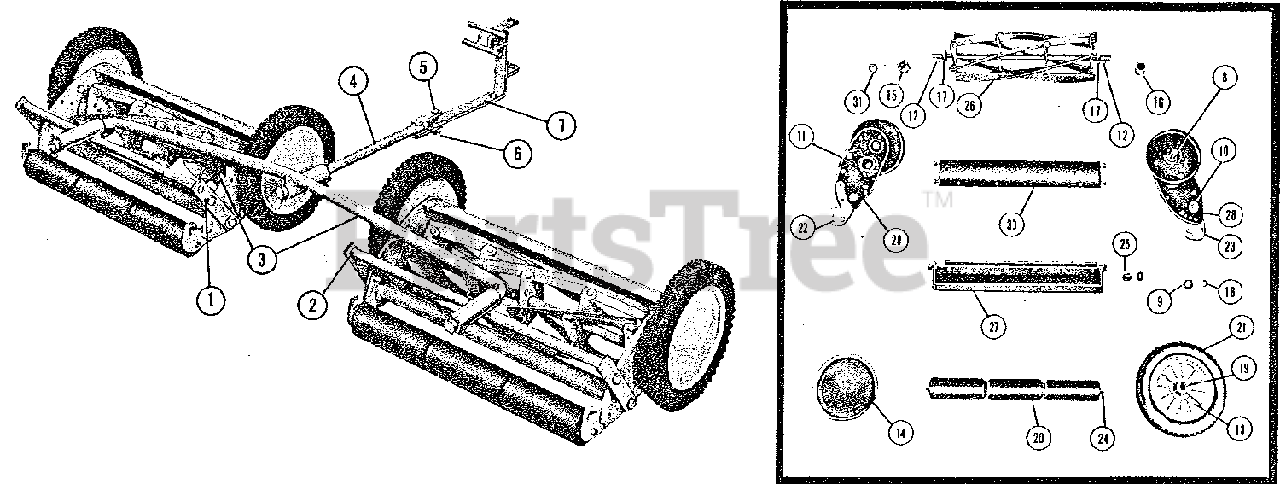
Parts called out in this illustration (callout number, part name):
1	SINGLE DRAW BAR ASSEMBLY, L.H. w/ 24" Mower, R.H. w/30" Mower
2	SINGLE DRAW BAR ASSEMBLY, R.H. w/ 24" Mower, L.H. w/30" Mower
3	DOUBLE DRAW BAR ASSEMBLY
4	TONGUE ASSEMBLY
5	TONGUE PIN
6	CLIP, Spring
7	FRAME EXTENSION ASSEMBLY
8	AXLE, Wheel
9	WASHER, Wheel Retaining
10	CAM, Adjusting
11	BEARING, Housing
12	DRIVING PAWL
13	WHEEL, Internal Gear
15	GEAR, Pinion, L.H.
16	GEAR, Pinion, R.H.
17	BEARING, Reel
18	RING, Retaining
19	BEARING, Wheel
22	BRACKET, Roller Retainer (L.H.)
23	BRACKET, Roller Retainer (R.H.)
24	SHAFT, Roller
25	BUSHING, Hitch
26	ASSEMBLY, Reel, 20"
27	BAR ASSEMBLY, Cutter, 20"
28	FRAME ASSEMBLY, R.H. Side
29	FRAME ASSEMBLY, L.H. Side
30	BAR ASSEMBLY, Brush, 20"
31	PINION, Gear Insert
